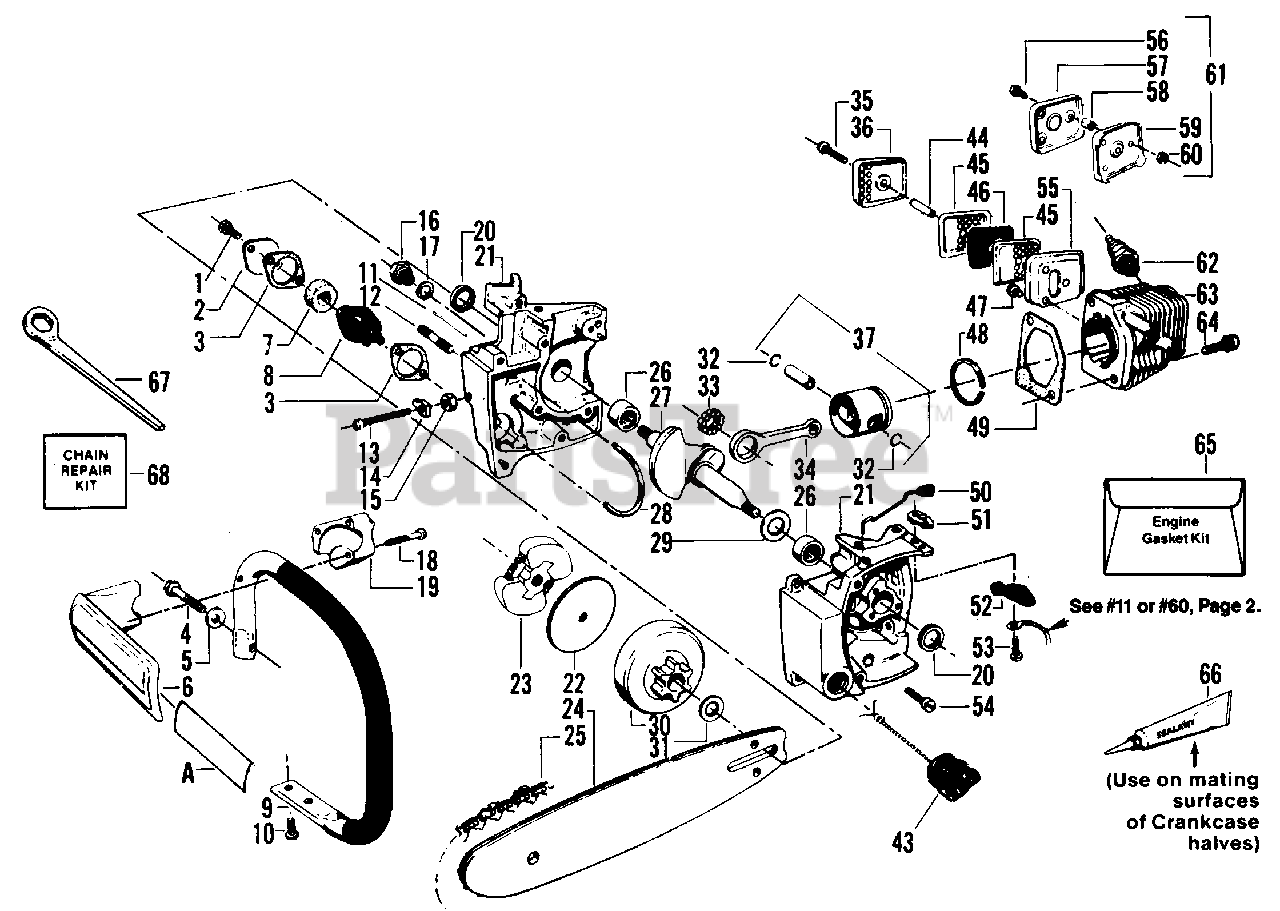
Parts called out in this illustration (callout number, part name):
1	Screw - 8 - 32 x 1/2
2	Cover Metering Body
3	Gasket - Oil Pump Metering Body
4	Screw - 1/4 - 20 x 1-1/4 Hex Bolt
5	Washer - Handlebar Top
6	Handguard
7	Filter - Oil Metering
8	Body Ass'y.
9	Handlebar Ass'y. - 12"
9	Handlebar Ass'y. - 14"
10	Screw - 10 - 24 x 5/8 Hex w/Head
11	Pin - Oil Tank Vent
12	Stud Bar
13	Screw - Bar Adj.
14	Pin - Bar Adj.
15	Lock Nut 8 - 32
16	Check Valve Kit - Oil Tank Pressure (Inc.17)
17	Gasket - Check Valve
18	Screw - Plastite
19	Cap - Handguard
20	Seal - Crankcase
21	Crankcase Ass'y. (Inc. #20 & 26)
22	Clutch Washer Kit See Service Reference # 3
24	Guide Bar 10" Non - Armor Tip
24	Guide Bar 10" Sprocket Nose
24	Guide Bar 12" Non - Armor Tip
24	Guide Bar 12" Sprocket Nose
24	Guide Bar 14" Sprocket Nose
24	Guide Bar 16" Sprocket Nose
25	Chain 10" (P101S-40)
25	Chain 12" (P101S-45)
25	Chain 14" (P101S-52)
25	Chain 16" (P101S-56)
26	Bearing Crankshaft
27	Crankshaft
28	Line - Oil Discharge (Bulk #8133)
29	Thrust Washer - Crankshaft
30	Sprocket & Drum
31	Spacer - Clutch (Inside)
32	Ring - Piston Pin Retainer
33	Bearing - Roller
34	Connecting Rod
35	Screw - 10 - 24 x 1-7/16
36	Cover - Muffler
37	Piston Kit (Inc. #32)
43	Oil Cap Ass'y. (Inc. O-Ring)
44	Spacer - Muffler Cover
45	Baffle - Muffler
46	Screen - Spark Arrestor
47	Screw - 10 - 24 x 1/2 Fil. Head
48	Piston Ring
49	Gasket - Cylinder
50	Knob Ass'y.
51	Ramp - Kill Switch
52	Clamp - Switch
53	Screw - 8 - 8/16 Tapping
54	Screw - 10 - 24 x 11/16 Phillip Pan Hd.
55	Body - Muffler
56	Screw - Hex Slotted 8 -32 x 7/16 (Optional)
57	Heat Shield (Optional)
58	Spacer - Cover (Optional)
59	Cover - Muffler (Optional)
60	Locking Nut 8 - 32 (Optional)
61	Cover & Shield Ass'y. (Inc. 56-60) (Optional)
62	Spark Plug CJ-8
63	Cylinder
64	Screw - 1/4 - 20 x 3/4 Socket Head
65	Engine Gasket/Kit (Inc.3,7,17,20,49)
66	Sealant - Crankcase
67	Bar Adjusting Tool
68	Chain Repair Kit
A	Decal - Kickback
